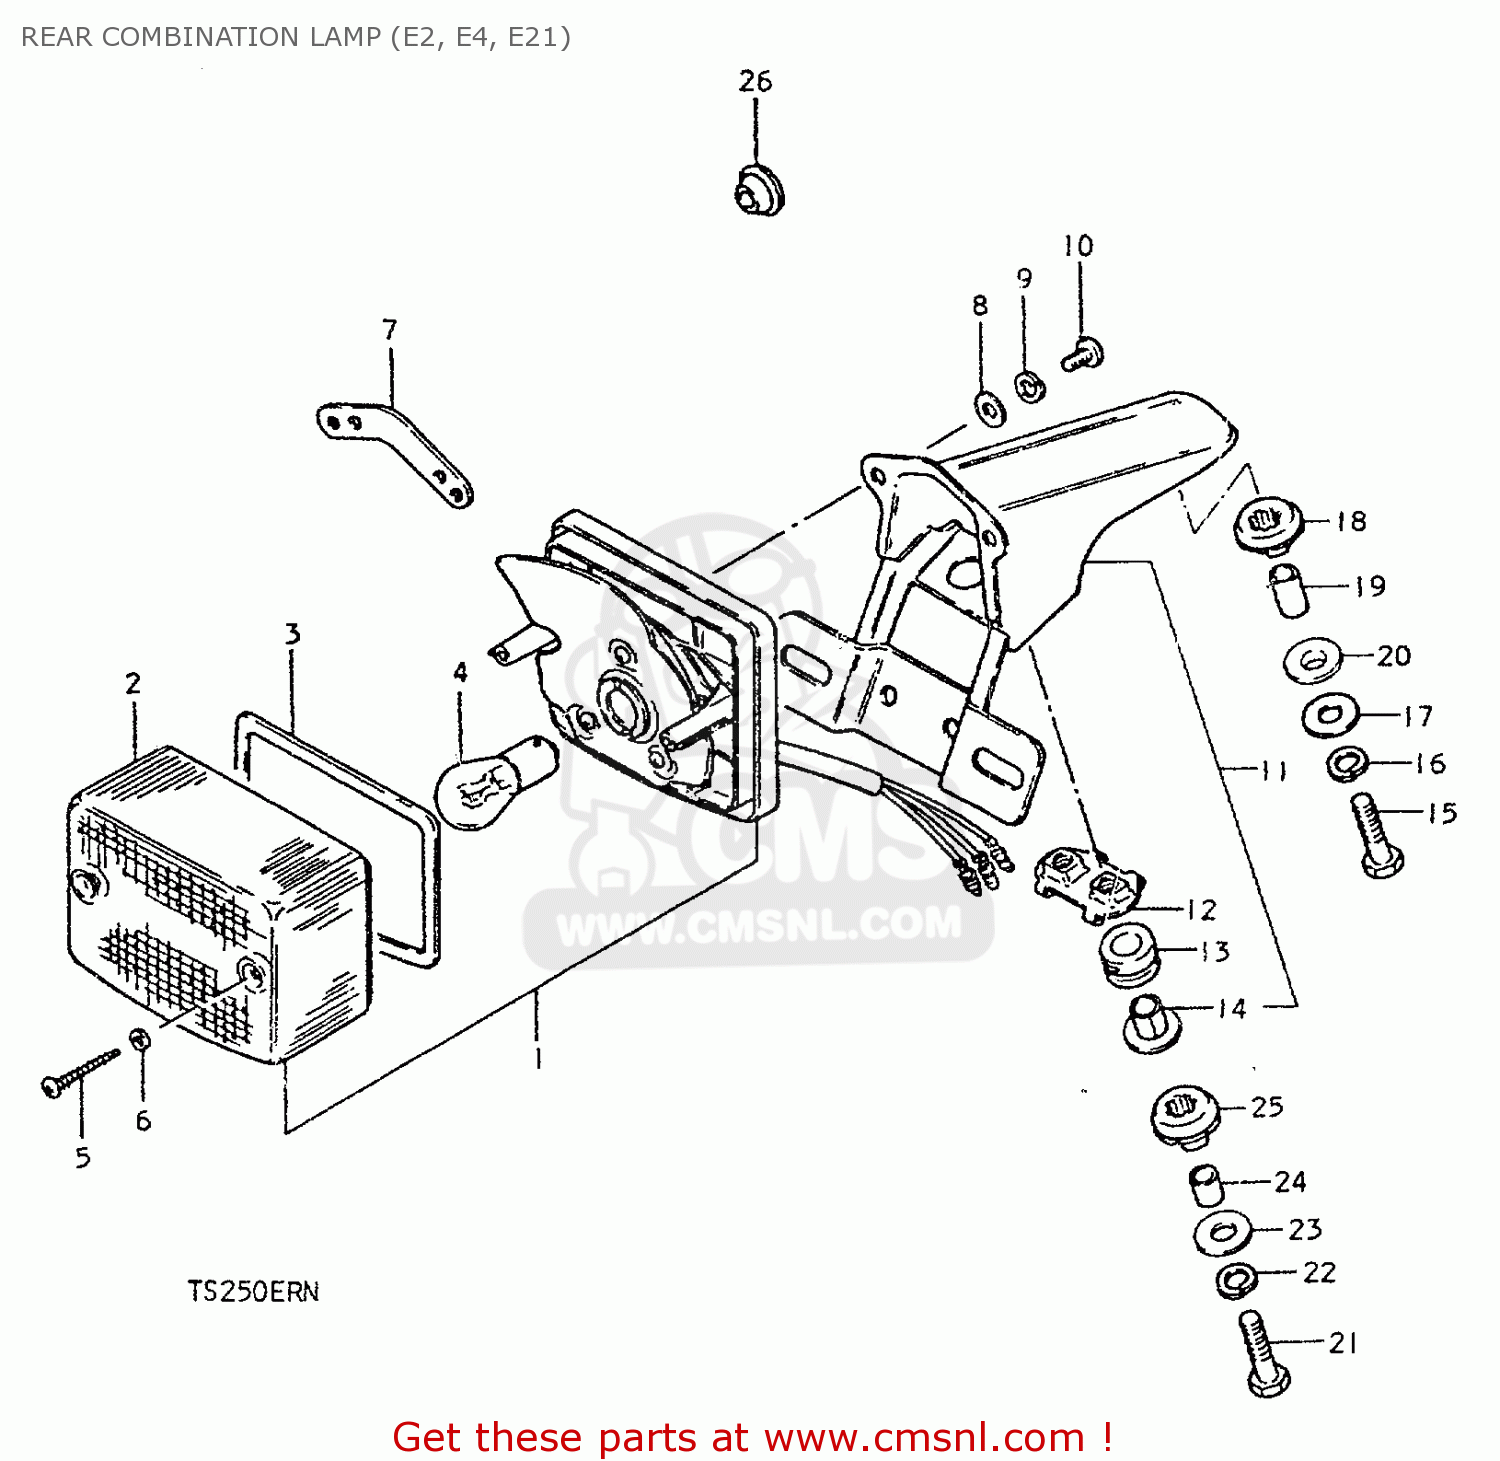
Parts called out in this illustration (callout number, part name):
1	LAMP UNIT, TAIL
2	LENS
3	GASKET (NAS)
4	BULB (6V,21/5W)
5	BOLT
6	GASKET (NAS)
7	PLATE,REAR COMBINATION LAMP
8	WASHER,5MM
9	WASHER,LOCK
10	SCREW
11	BRACKET ASSY
12	PLATE
13	CUSHION
14	SPACER
15	BOLT
16	LOCK WASHER
17	WASHER (6.5X20X1.2)
18	CUSHION
19	SPACER
20	CUSHION
21	BOLT
22	LOCK WASHER
23	WASHER (6.5X20X1.2)
24	SPACER
25	CUSHION
26	GROMMET
